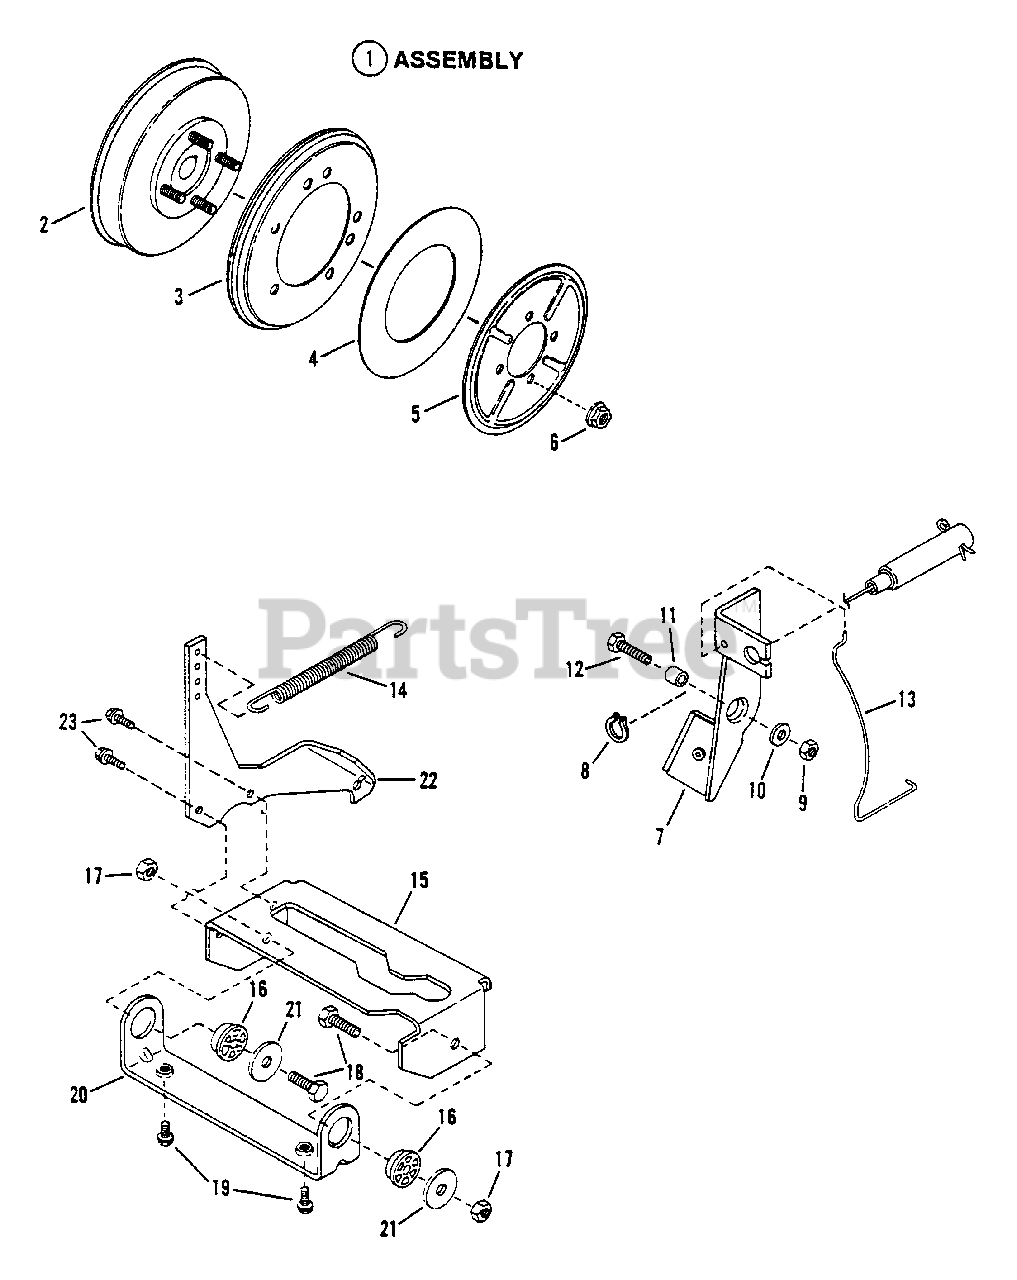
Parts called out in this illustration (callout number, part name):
1	ASSEMBLY, Smooth Clutch
2	HUB, Driven Disc
3	DISC, Driven
4	WASHER, Thrust
5	PLATE
6	NUT, 5/16-18 Hex Flange lock
7	ASSEMBLY, Brake Lever
8	RING, Retaining
9	NUT, 1/4-28 Hex Top Lock
10	WASHER, 1/4 Flat
11	SPACER
12	SCREW, 1/4-28 x 1" Hex Head Cap
13	SPRING, Brake Return
14	SPRING, Clutch Brake
15	LIFT, Yoke
16	BEARING, Yoke
17	NUT, 5/16-24 Hex Center Lock
18	SCREW, 5/16-24 x 1" Hex Head Cap
19	SCREW, 3/8-16 x 1/2" Self-Tapping
20	COLLAR, Yoke
21	WASHER, 5/16 Flat
22	ARM, Yoke
23	SCREW, 1/4-20 x 3/8" Self-Tapping
